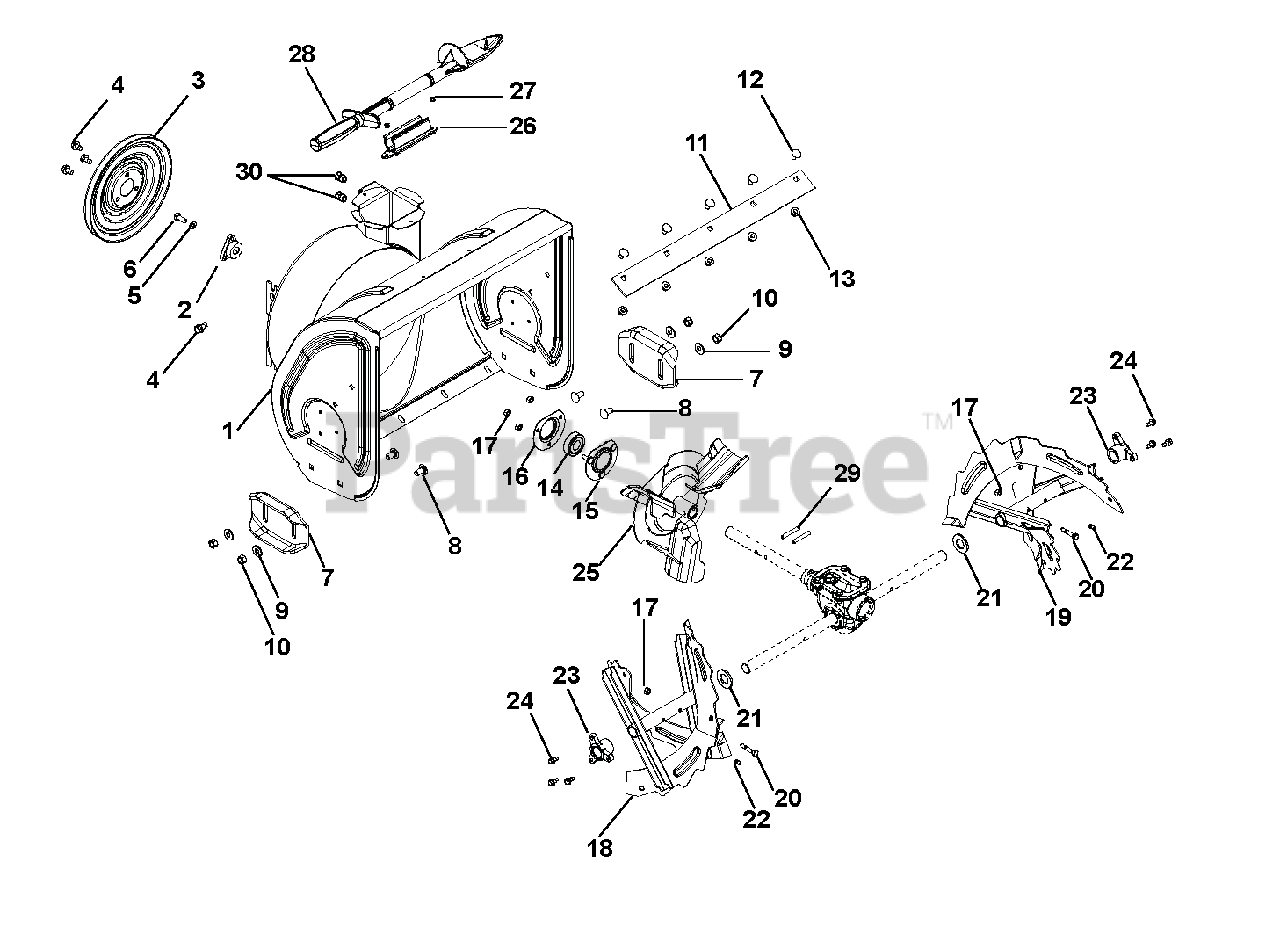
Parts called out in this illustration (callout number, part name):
1	BLOWER HOUSING, 20" BLACK
2	PULLEY HUB, BOLT-ON D-BORE .75
3	PULLEY,SPIN FORM SINGLE GROOVE
4	@SCR-TAP .31-18X.50 HWH TR YWZ
5	WSHR-LK .312X.097 HVY YWZC
6	BLT-HEX .31-24X.75 YWZC GR5
7	SKID SHOE, REVERSIBLE - BLACK
8	@BLT-RHDSSQNK .38-16X.75 G5YZ
9	@WSHR-FL-STL.38X.875X.083 YWZC
10	@NUT-LK-CTR .38-16 YWZC
11	BLADE, SCRAPER 20" COMPACT BLK
12	BOLT, MODIFIED HEAD CARRIAGE
13	@NUT-LK-TOP-FLG .31-18 YWZC
14	BRG-BALL .750X1.750X.50
15	BEARING FLANGE
16	BEARING FLANGE
17	@NUT-LK-CTR .25-20 YWZC
18	AUGER, 20" RH, BLK SERR W/ZERK
19	AUGER, LH 20", BLK SERR W/ZERK
20	SHEAR BOLT WITH NUT
21	@WSHR-FL-STL.812X1.50X.135YWZC
22	ZERK,FITTING .25X.125 DRIVE IN
23	BUSHING, RAKE SHAFT .75"
24	SCR-TAP .25-20X.50 HWH TR YWZ
25	IMPELLER, COMPACT 12" 3-BLADE
26	MOUNT, SNOW CLEAN OUT
27	RVT-POP .187 YZ
28	DEVICE, SNOW CLEAN OUT
29	PIN-ROLL .250X1.75
30	NUT, THREADED INSERT .38-16
